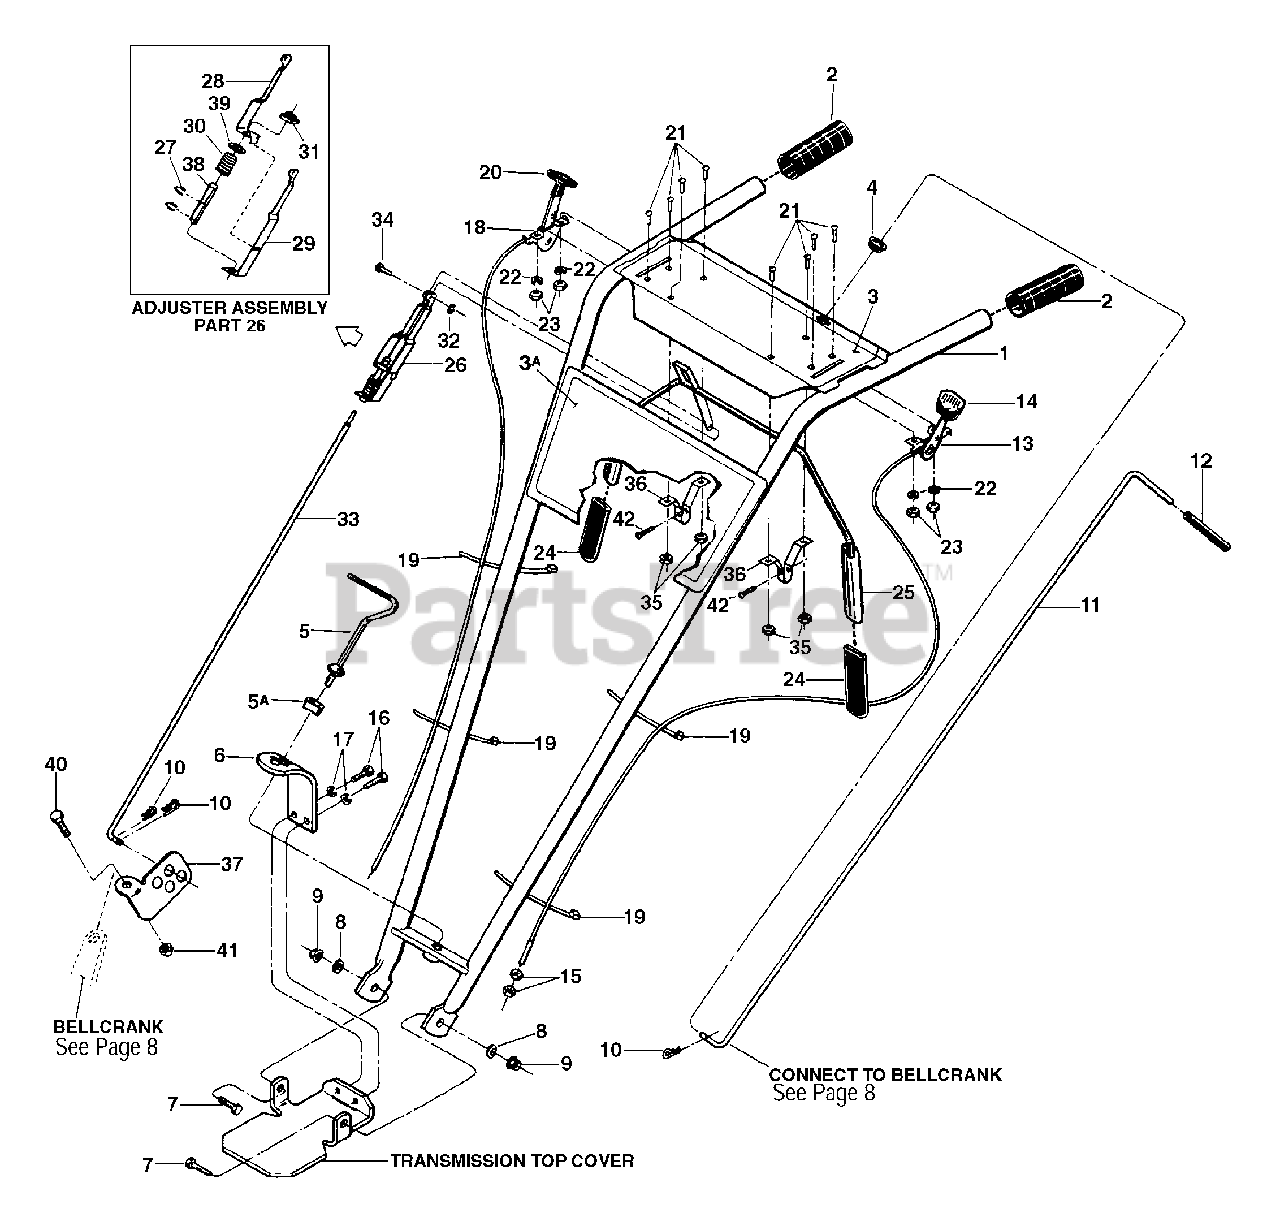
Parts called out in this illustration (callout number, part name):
1	Handlebars
2	Grip, handlebars
3	Decal-Operator Control Panel
3A	Decal-Troy-Bilt logo
4	Grommet, plastic
5	Handle, height adj
5A	Washer, keyed
6	Bracket, handlebar height adjustment
7	Screw, hex hd., 3/8-16 x 1, GR5
8	Washer-flat, 3/8, S.A.E
9	Locknut, hex hd., 3/8-16
10	Cotter, hairpin
11	Lever, clutch-maneuvering
12	Grip, clutch lever
13	Wheel gear control & cable assy.
14	Knob, wheel gear control lever
15	Nut-hex, 5/16-24
16	Screw, hex hd., 3/8-16 x 3/4
17	Lockwasher, 3/8
18	Engine throttle control & cable
19	Ties, plastic
20	Knob, engine throttle lever
21	Screw, No. 10-32 x 1/2
22	Lockwasher, No. 10
23	Nut, hex hd. No. 10-32
24	Grip, paddle
25	Bail, forward clutch control
26	Adjuster assy.
27	Klip ring
28	Adjuster, Right side
29	Adjuster, Left side
30	Spring, adjuster
31	Nut, rectangular
32	Klip ring
33	Rod, forward clutch
34	Pin, Clevis
35	Sems Nut
36	Bracket, bail support
37	Swivel
38	Bushing
39	Washer
40	Screw, hex hd., 1/4-20 x 3/4
41	Nut, 1/4-20
42	Screw, flanged hex hd., self-tapping, 1/4-20 x 1/2
